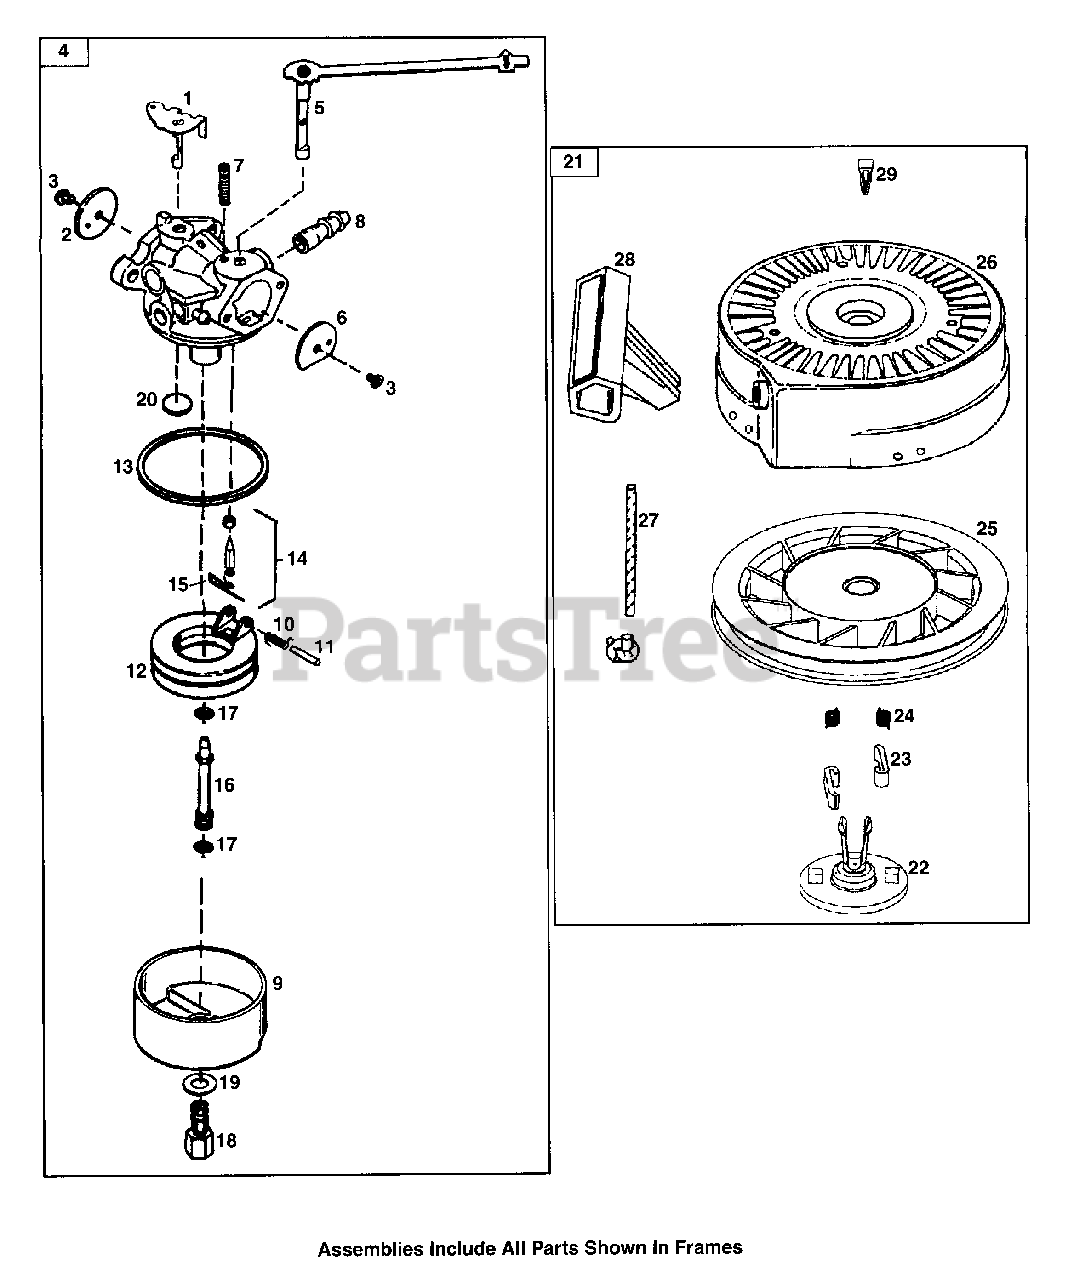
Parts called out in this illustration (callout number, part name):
1	Throttle Shaft & Lever Ass'y
2	Throttle Shutter
3	Shutter Screw
4	Carburetor Assembly
5	Choke Shaft & Lever Ass'y
6	Choke Shutter
7	Choke Positioning Spring
8	Fuel Fitting
9	Float Bowl
10	Float Dampening Screw
11	Float Shaft
12	Float
13	Float Bowl O-Ring
14	Inlet Needle, Seat & Clip
15	Spring Clip
16	Main Nozzle Tube
17	O-Ring Main Nozzle Tube
18	High Speed Bowl Nut
19	Bowl Nut Washer
20	Welch Plug, Atmospheric Vent
21	Rewind Starter Ass'y
23	Starter Dog
24	Dog Spring
25	Pulley Ass'y
26	Starter Housing Ass'y
27	Starter Rope (98")
28	Starter Handle
29	Locking Tab
